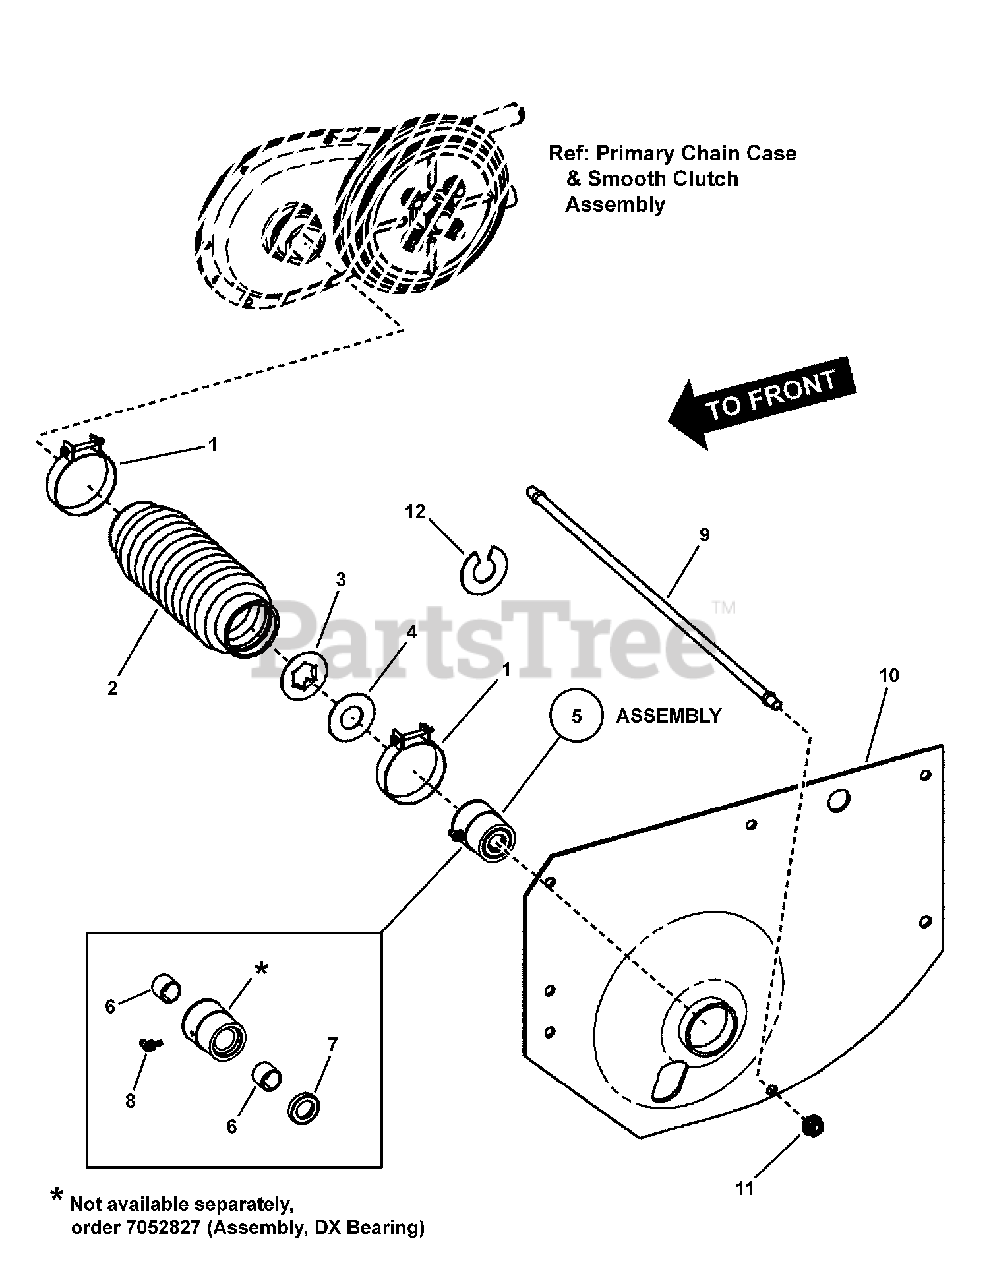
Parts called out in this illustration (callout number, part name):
1	CLAMP, 2" ID
2	BOOT, Rear Axle, Thick Flange
3	WASHER, Thrust
4	THRUST WASHER
5	ASSEMBLY, DX Bearing
6	BEARING, 3/4" I.D. DX
7	SEAL, .750 x 1.250 x .250 (Dust/Grease)
8	FITTING, Lube, 45 Degree, 3/16" w/Hex (long shank)
9	TIE ROD, (5/16-24 thread- both ends)
10	FENDER, Left Hand (1.628" I. D. Hole)
11	NUT, 5/16-24 Flange Lock (Large)
12	WASHER, Shim
